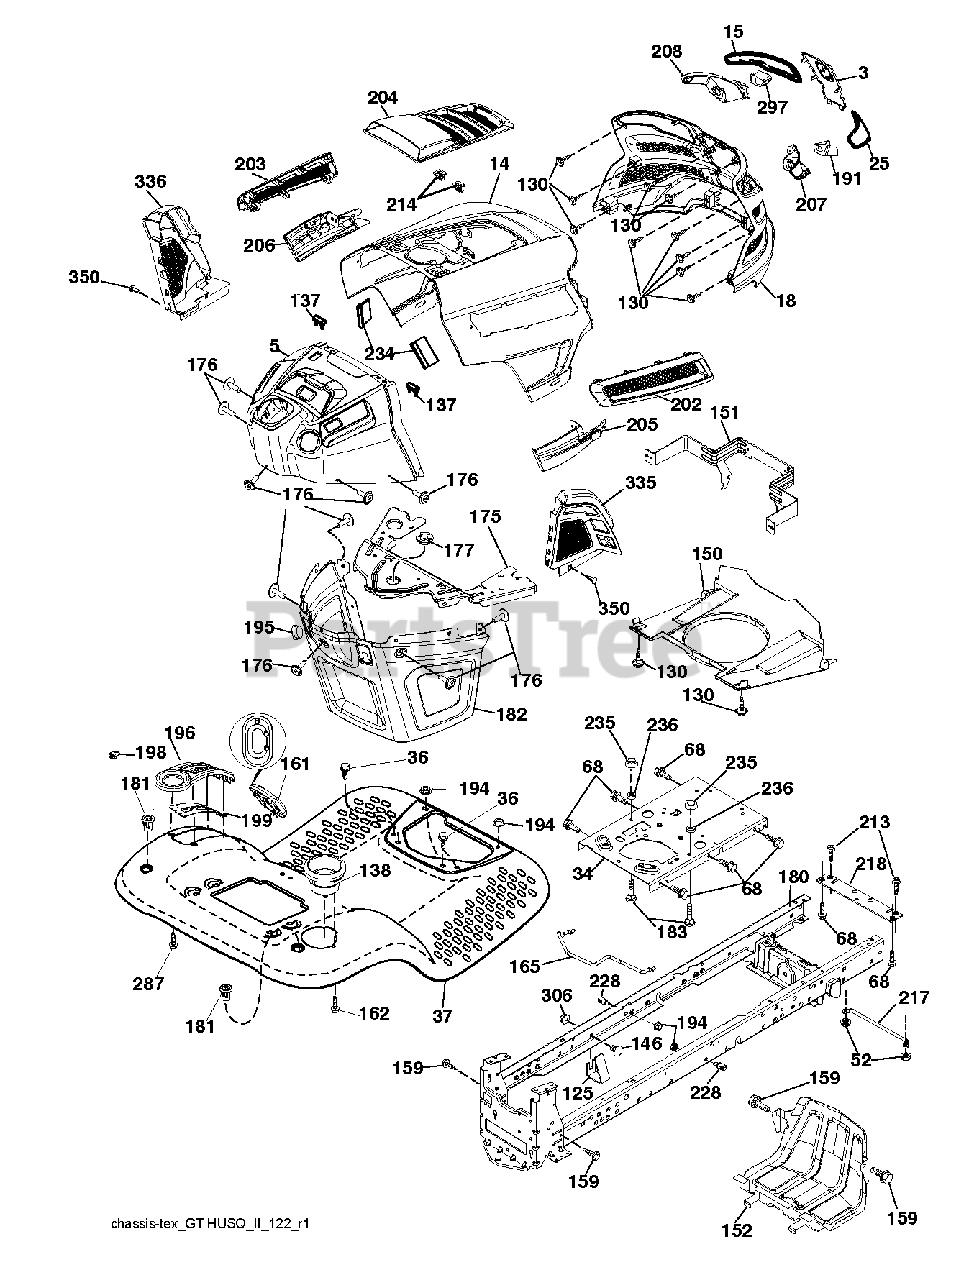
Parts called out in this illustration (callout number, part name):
3	APPLIQUE.SUBASM.GT.HUSQ.II
5	DASH.UPPER.ASSY.GT2.GREY
14	HOOD.ASM.HUSQVARNA.GT.TEX.ORAN
15	LENS.HEADLIGHT.LH.GTII.2011
18	GRILLE.SUBSTRATE.2011.
25	LENS.HEADLIGHT.RH.GTII.2011
34	PLATE.ENGINE.WELDED.CHASSIS
36	SCREW 5/16"
37	FENDER.ERGO.LT.W/CPH.W/FW.ORNG
52	LOCKNUT
68	SCREW LT
125	CLIP.FUEL.LINE
130	SCREW.#10 X 0.750.BOS
137	BUMPER DASH
138	HOLDER.CUP.LT.GREY
146	BOLT.RDHD.SHT.SQNK.3/8-16X5/8
150	AIR.DUCT.GTV.BLACK
151	BRACKET.PIVOT.HOOD.GT.HUSQ.II
152	SHIELD.BROWNING.PNT.GT.V2
159	SCREW, 3/8-16X3/4
161	WINDOW.FUEL.LT.HUSQ.TEX.498
162	SCREW.HI-LO.CONSOLE
165	SUPPORT.TANK.REAR.W/TEX
175	PLATE.CROSSMEMBER.HUSQ
176	SCREW.#10-24X5/8.RN.QU
177	BUSHING, STEERING
180	CHASSIS
181	BUSHING.MNT.FEND.CRGO.TEX.49
182	DASH.LOWER.COMMON.12V.ADAPTOR
183	BOLT.5/16-18X1-1/4 FULL THD
191	INSERT.REFLECTIVE.RH.HUSQ.GTII
194	NUT LOCK HEX FLANGE 5/16-18
195	PLUG.HOLE.DASH.LOWER.12V.BLK
196	DECKLFT.CONSOL FULL ASSM GREY
198	INDICATOR.DECK.LIFT.RED
199	PLATE.DECK.LIFT.HUSQ.LT
202	VENT.SIDE.RH.GT.HUSQ.II.
203	VENT.SIDE.LH.GT.HUSQ.II.498
204	VENT.TOP.HUSQ.GT2
205	SIDE.TRIM.RH.GT.HUSQ.II
206	SIDE.TRIM.LH.GT.HUSQ.II.GRAY
207	BEZEL LIGHT.RH.GT.II.MYLAR
208	BEZEL LIGHT.LH.GT.II.MYLAR
213	BOLT
214	CLIP.RETAINER.TINNER.
217	ROD.PIVOT.HOOD
218	X-PIECE.HOOD.STOP.NON/
228	STUD.FASTNER.W/ANTI-ROTATE
234	BUMPER.HOOD.TEX.HUSQVARNA
235	SPACER FENDER
236	NUT.CENTERLOCK.5/16-
287	SCREW 1/4X20
297	INSERT.REFLECTIVE.LH.HUSQ.GTII
306	NUT LOCK FLG 3/8-16 UNC
335	COVER.LOWER.DASH.RH.BLACK
336	COVER-LH.LOWER.DASH.GT2.BLACK
350	CLIP.X-MAS.TREE
